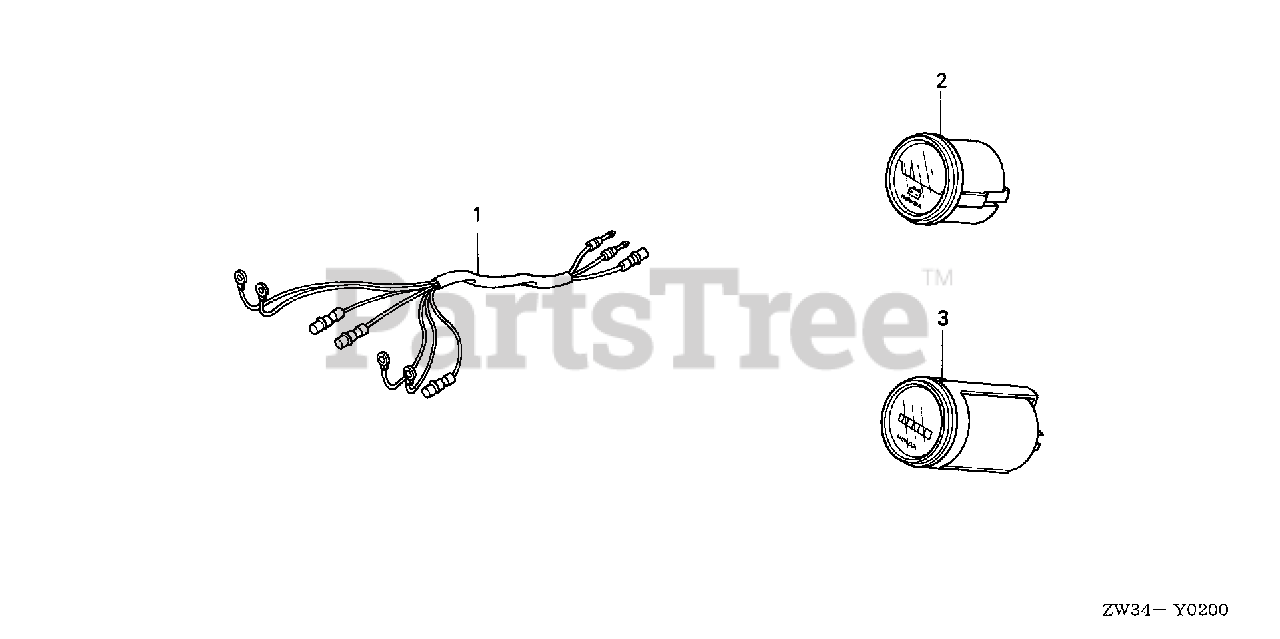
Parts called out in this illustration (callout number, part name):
1	HARNESS ASSY., METER (B)
2	METER ASSY., VOLT (NOT AVAILABLE: USE 37453-ZW5-000ZA)
3	METER ASSY., HOUR L.C.D.
